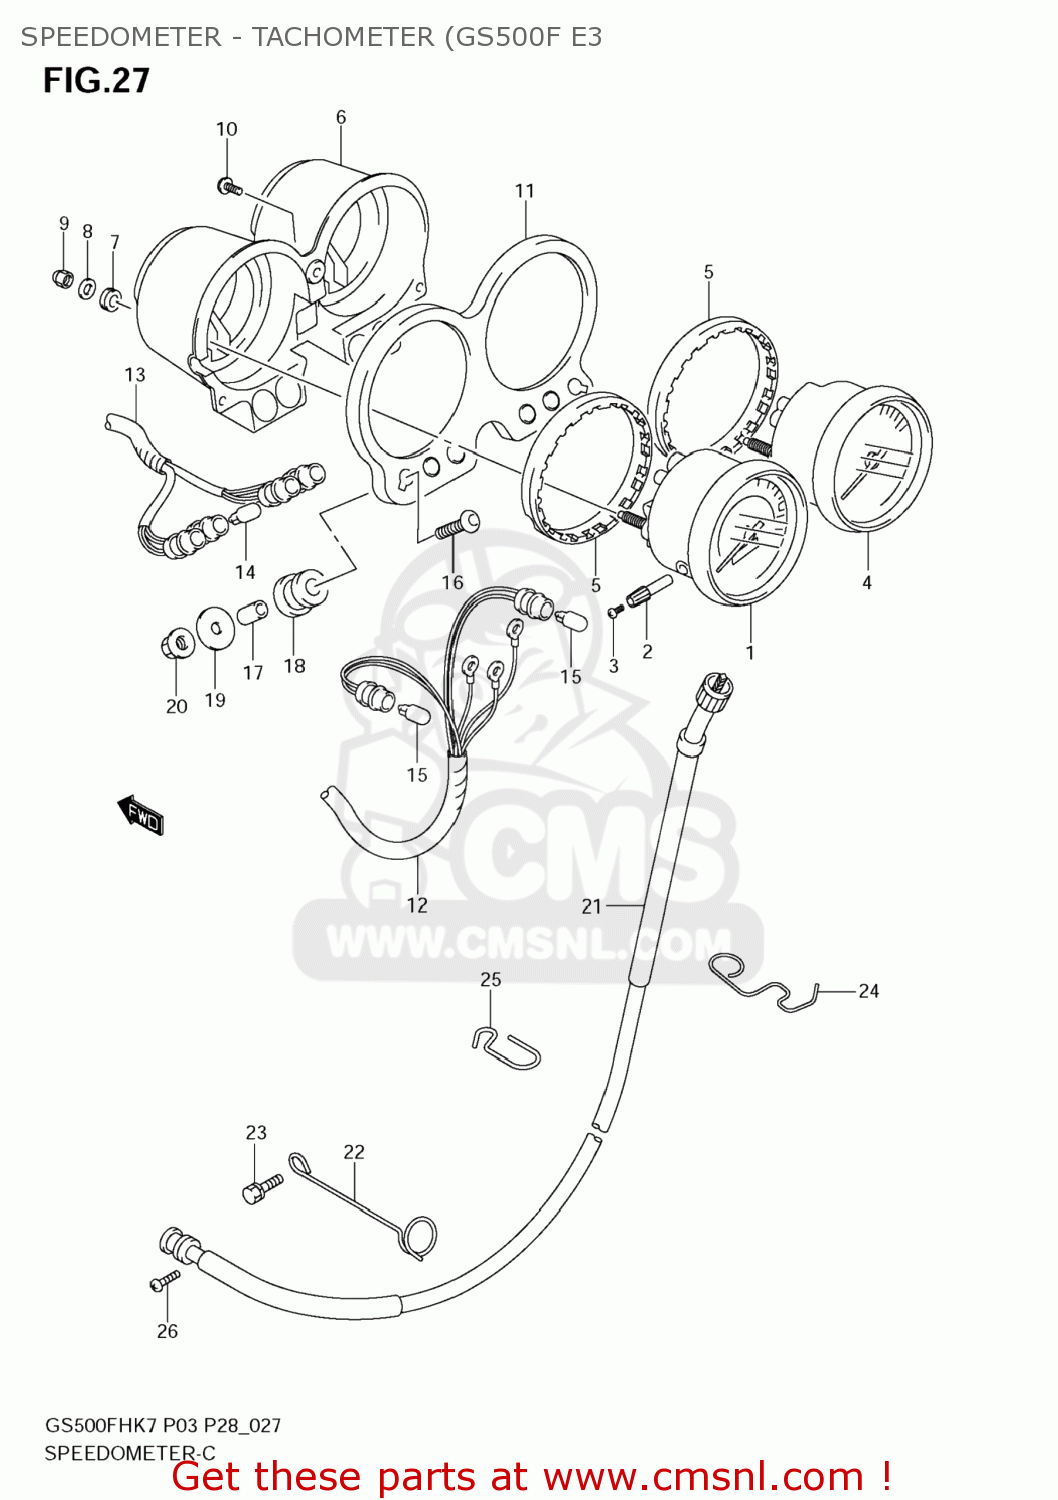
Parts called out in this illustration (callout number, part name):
1	SPEEDOMETER
2	KNOB
3	ROTOR,SPEED
4	TACHOMETER
5	DAMPER
6	COVER
7	CUSHION
8	WASHER
9	NUT
10	SCREW
11	BRACKET METER
12	SOCK.&CORD PIL
13	SOCK.&CORD,PIL
14	BULB (12V, 1.7W, T6.5)
15	BULB(12V1.7W,T10)
16	BOLT(6X30)
17	SPACER(6.4X9X17)
18	CUSHION,METER BRACKET
19	WASHER(6.5X28X1.6)
20	NUT
21	CABLE ASSY,SPEEDOMETER
22	GUIDE,CABLE NR
23	BOLT
24	GUIDE,CABLE NR
25	GUIDE,CABLE NR
26	SCREW
